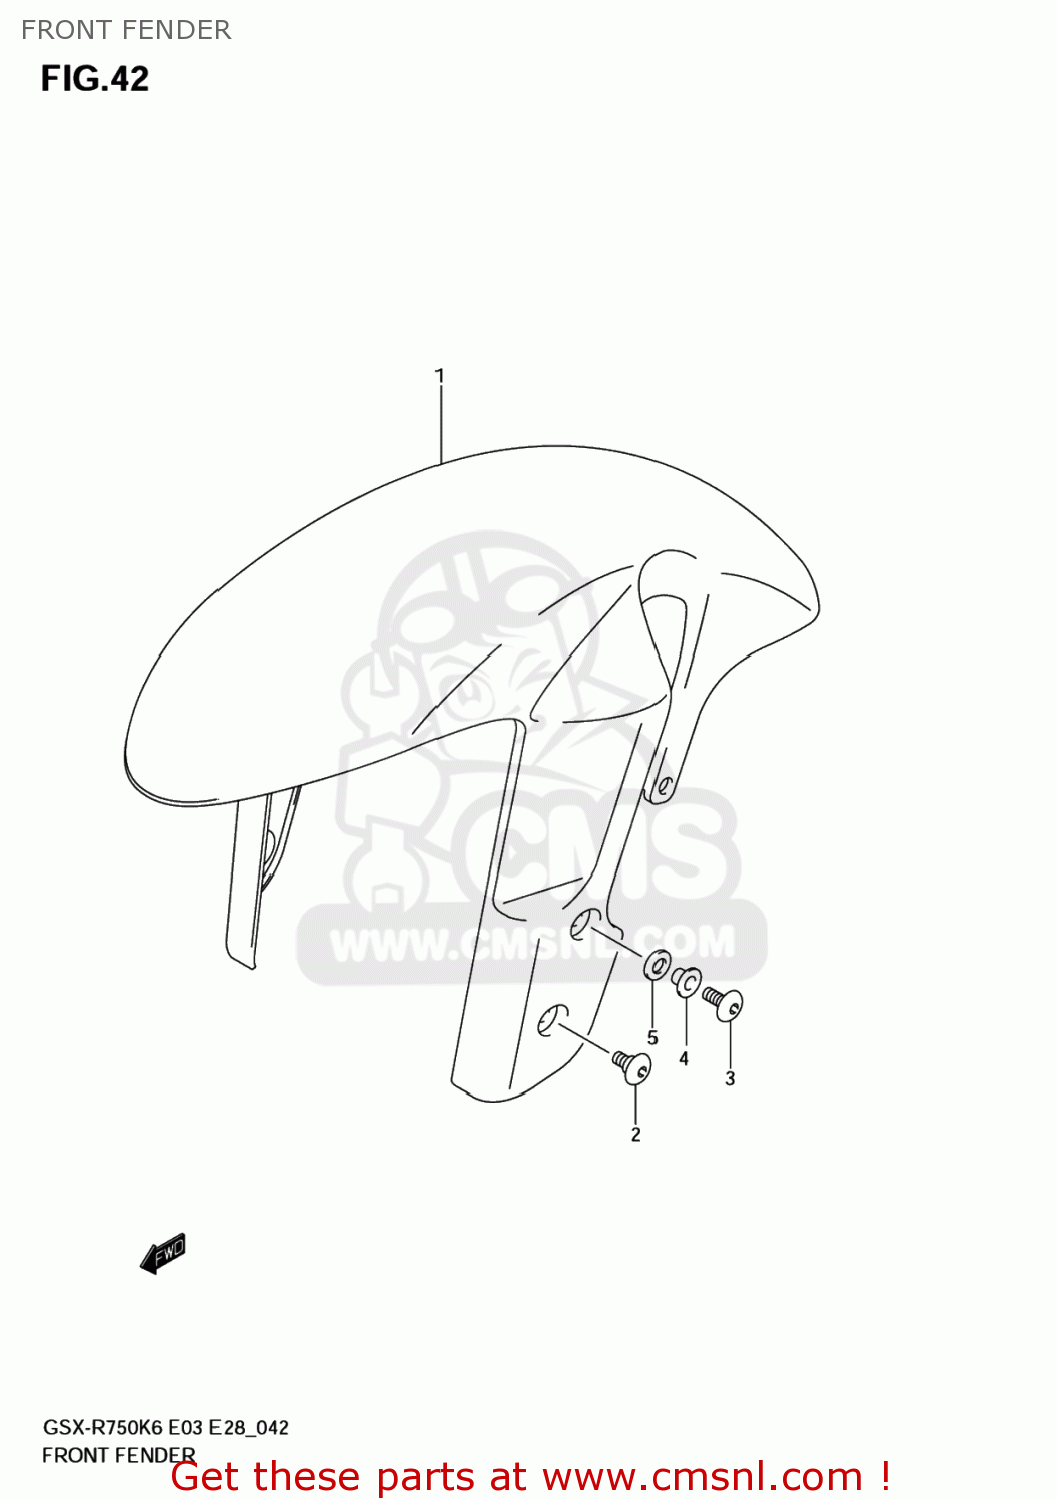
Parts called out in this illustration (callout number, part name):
1	FENDER,FR
2	SCREW(6X12)
3	SCREW(6X16)
4	WASHER
5	WASHER,FR FENDER FR NO.2
